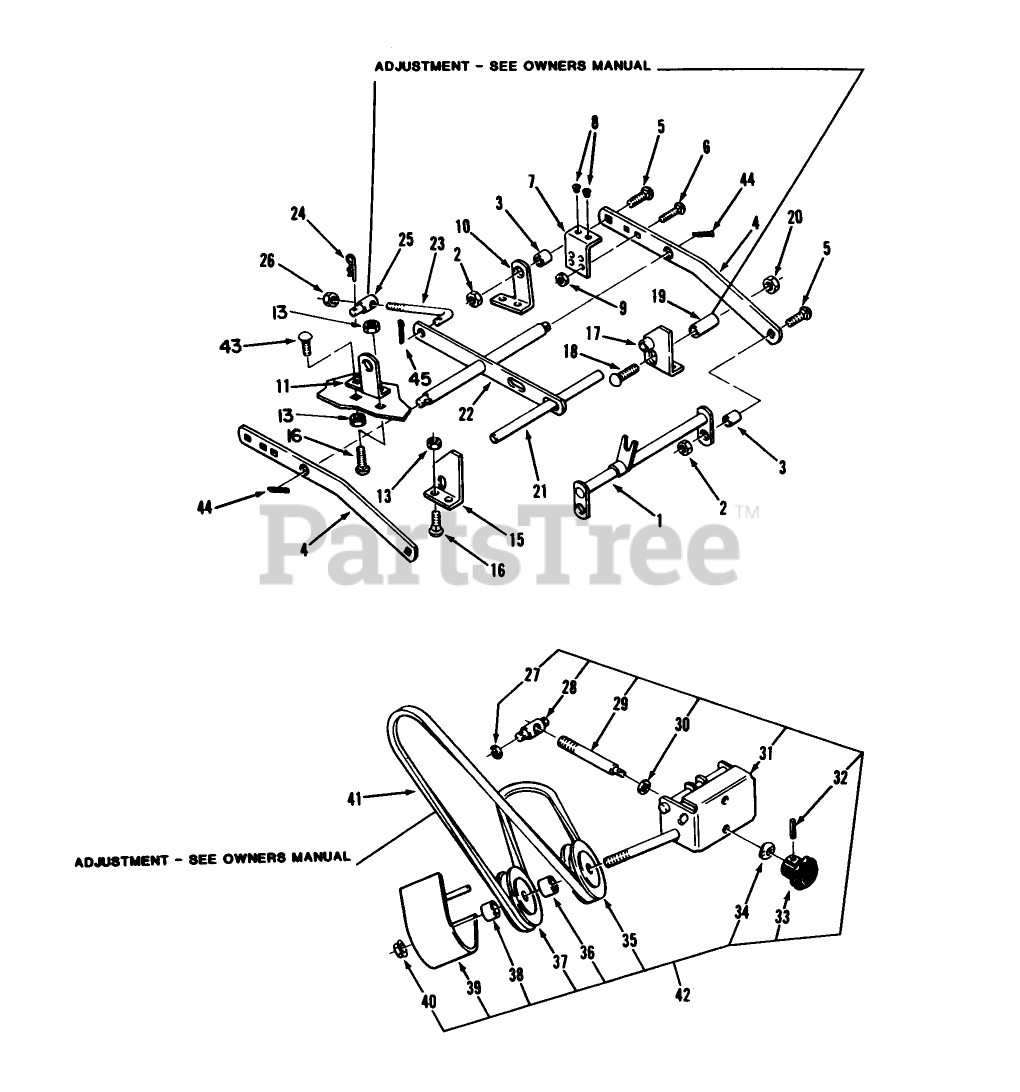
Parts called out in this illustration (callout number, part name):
1	Hitch
2	LOCKNUT-FLANGE
3	SPACER
4	Bar Draft
5	Bolt
6	Bolt-Carriage
7	Bumper-Metal
8	BUMPER-RUBBER
9	Nut
10	LH Rear Bracket
11	Rear Bracket RH
13	Nut
15	Front Bracket RH
16	Bolt-Carriage
17	Front Bracket LH
18	CARRIAGE BOLT -4
20	Nut
21	Front Shaft
22	Leveler
23	ROD-LEVEL ADJUST
24	Hairpin
25	TRUNNION-LIFT
26	NUT
27	RING-RETAINING
28	TRUNNION-DOUBLE
29	ROD ADJ
30	Washer
31	Front Support
32	PIN-ROLL
33	KNOB-ADJUSTMENT
34	WASHER-SPRING
35	Pulley-V
36	SPACER
37	PULLEY-FLAT IDLER
38	SPACER-OUTER
39	Belt Cover
40	Nut
41	V-BELT
42	ASM-SUPPORT,IDLER
43	Bolt
44	Cotter Pin
45	Cotter Pin
